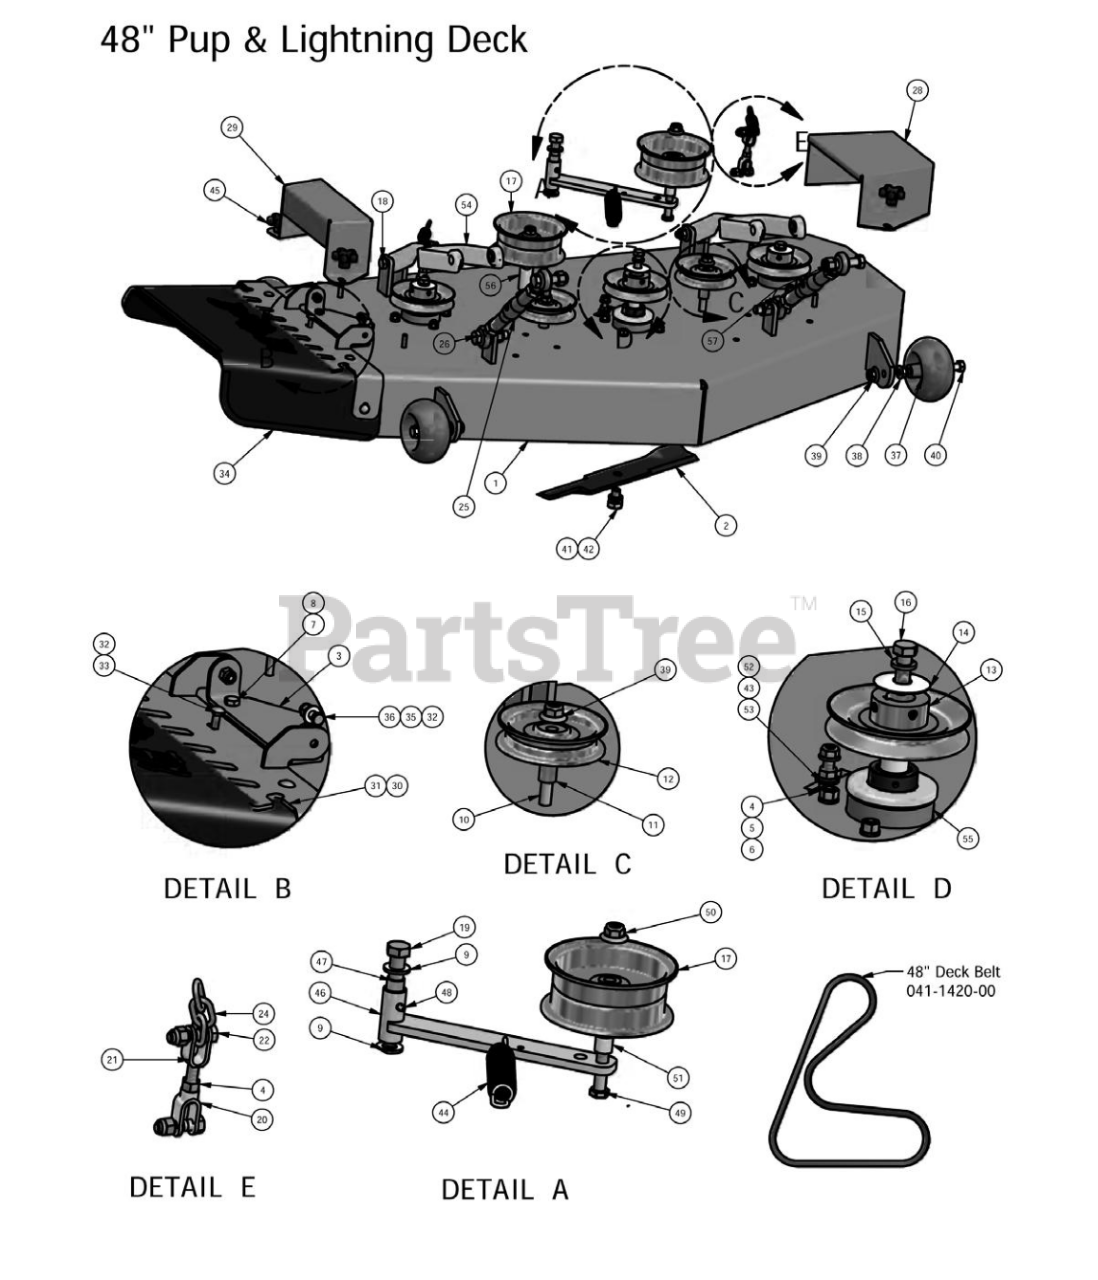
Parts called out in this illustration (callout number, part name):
1A	Complete Deck with Spindles
1B	48" Deck Belt
2	Fusion Blade
3	Discharge Chute Hanger (deck mounted)
4	3/8" Hex Nut
5	3/8" Lock Washer
6	3/8" x 1 1/4" Hex Bolt
7	3/8" x 3/4" Hex Bolt
8	3/8" Flange Nut
9	.635 ID Plastic Washer
10	1/2 x 3 1/2 Flange Bolt - Grade 8
11	Pup Pulley Spacer
12	4 3/4" Idler Pulley
13	5" Deck Pulley
14	Cup Washer
15	1/2" Lock Washer
16	1/2"-20 x 1 1/2 - Grade 5 Fine Thread Bolt
17	5 3/4" Deck Idler Pulley
18	1/2" x 2 3/4" Hex Bolt
19	5/8" x 4" Hex Bolt
20	Female Yoke
22	3/8" x 1 1/2" Hex Bolt
23	3/8 Nylock Nut
24	3" Chain Assembly
25	Turnbuckle (Top Link)
26	5/8" x 2 1/2" Hex Bolt
27	5/8" Nylock Nut
28	Pulley Cover
29	48" Spindle Cover
30	48" Lower Hanger
31	48" Discharge Chute Upper Hanger Plate
32	5/16" Nylock Flange Nut
33	5/16" x 1 1/4" Carriage Bolt
34	Rubber Discharge Chute
35	360 ID Plastic Washer
36	5/16" x 1" Hex Bolt
37	Anti-Scalp Rollers
37A	Deck Wheel Assembly
38	1/2" Flange Nut
39	1/2-13 Nylon Flange Nut-Orange
40	1/2" x 4" Bolt (Grade 8)
41	5/8" Lock Washer
42	5/8-18 GR 8 Hex Bolt
43	3/8" x 1 1/4" Carriage Bolt
44	Deck Idler Spring 2009
46	Deck Idler Arm 2009
47	5/8" Brass Bushing
48	1/4" Drive-in Grease Fitting
49	1/2" x 3" Bolt
50	1/2-13 Nylon Flange Nut-Orange
51	3/4 OD x 1/2 ID x 314 Length Spacer
52	3/8" Nylock Flange Nut
53	3/8" Flat Washer
54	Deck Arm Assembly
55	Double Bearing Spindle (Complete)
56	1 3/4 Pulley Spacer
57	5/8 Std NC Nylock Nut
